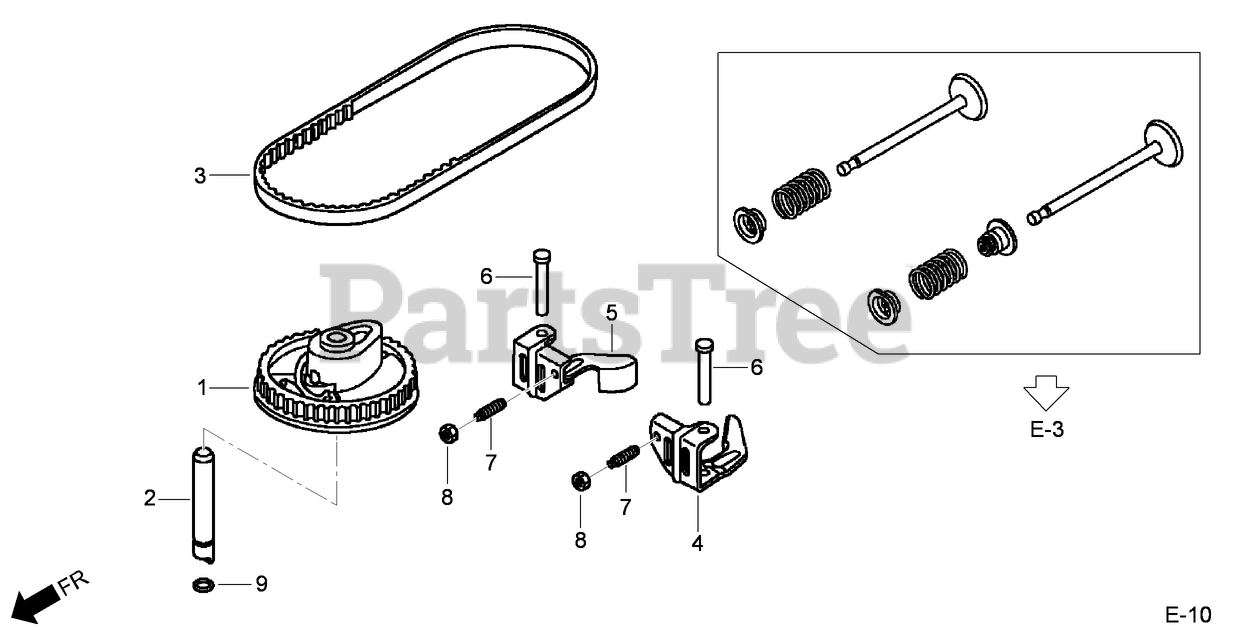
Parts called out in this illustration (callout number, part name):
1	PULLEY-CAMSHAFT
2	SHAFT-PULLEY, CAM
3	BELT-TIMING (84H U7 G-200)
4	ARM-ROCKER, INTAKE VALVE
5	ARM-ROCKER, EXHAUST VALVE
6	SHAFT-ARM, ROCKER
7	SCREW-ADJUSTING, TAPPET
8	NUT-ADJUSTING, TAPPET
9	O-RING (6.8X19) (ARAI)
